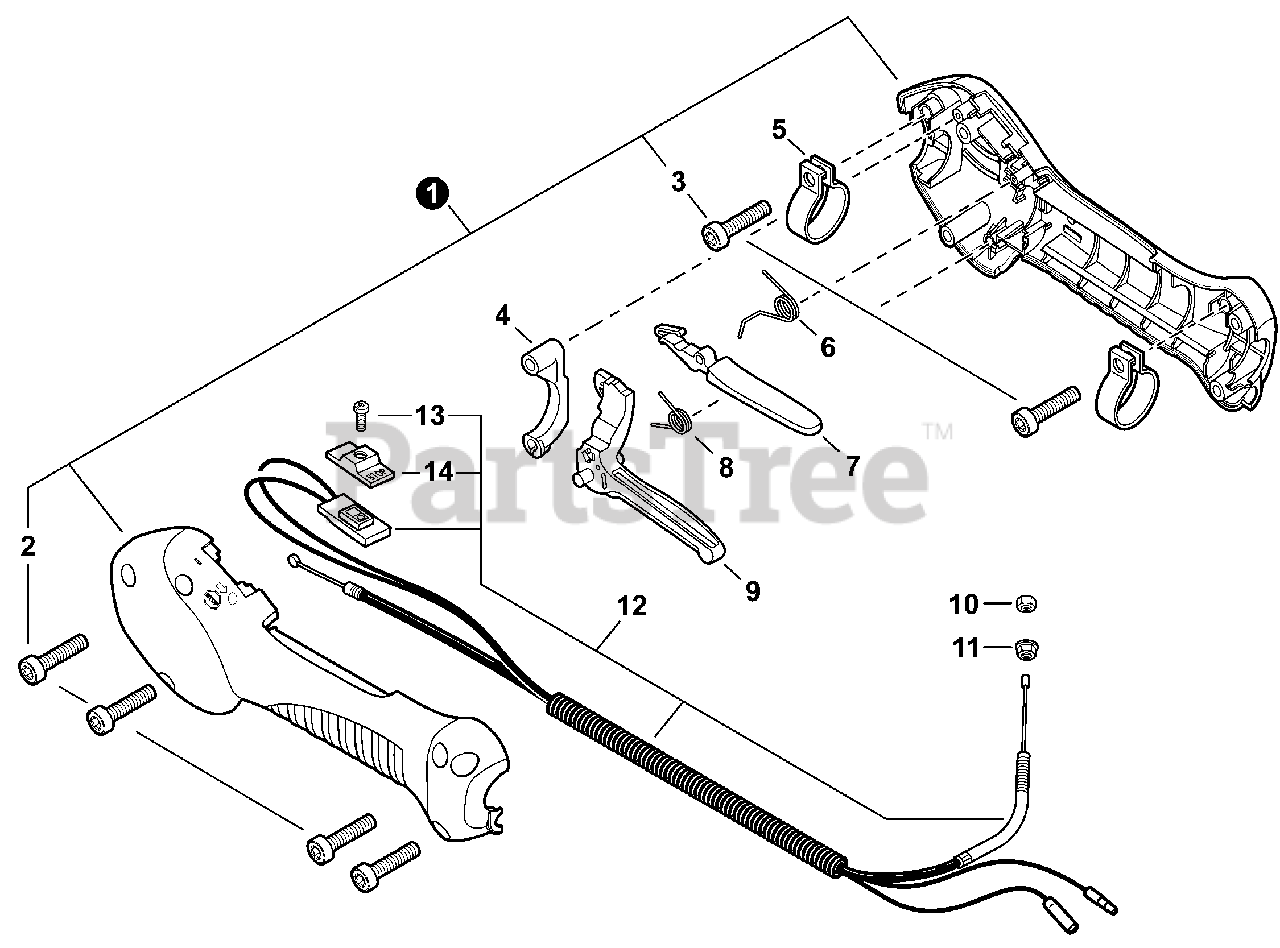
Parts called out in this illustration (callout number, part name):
1	CONTROL HANDLE KIT
2	BOLT, TORX 4×20
3	BOLT, TORX 5×20
4	LOCKOUT, THROTTLE
6	SPRING, TORSION
7	LEVER, THROTTLE LOCKOUT
8	SPRING, TORSION
9	TRIGGER, THROTTLE
11	NUT, FLANGE M6
12	CABLE ASSY, CONTROL
13	SCREW 3×10
14	KNOB, SWITCH - ORANGE
